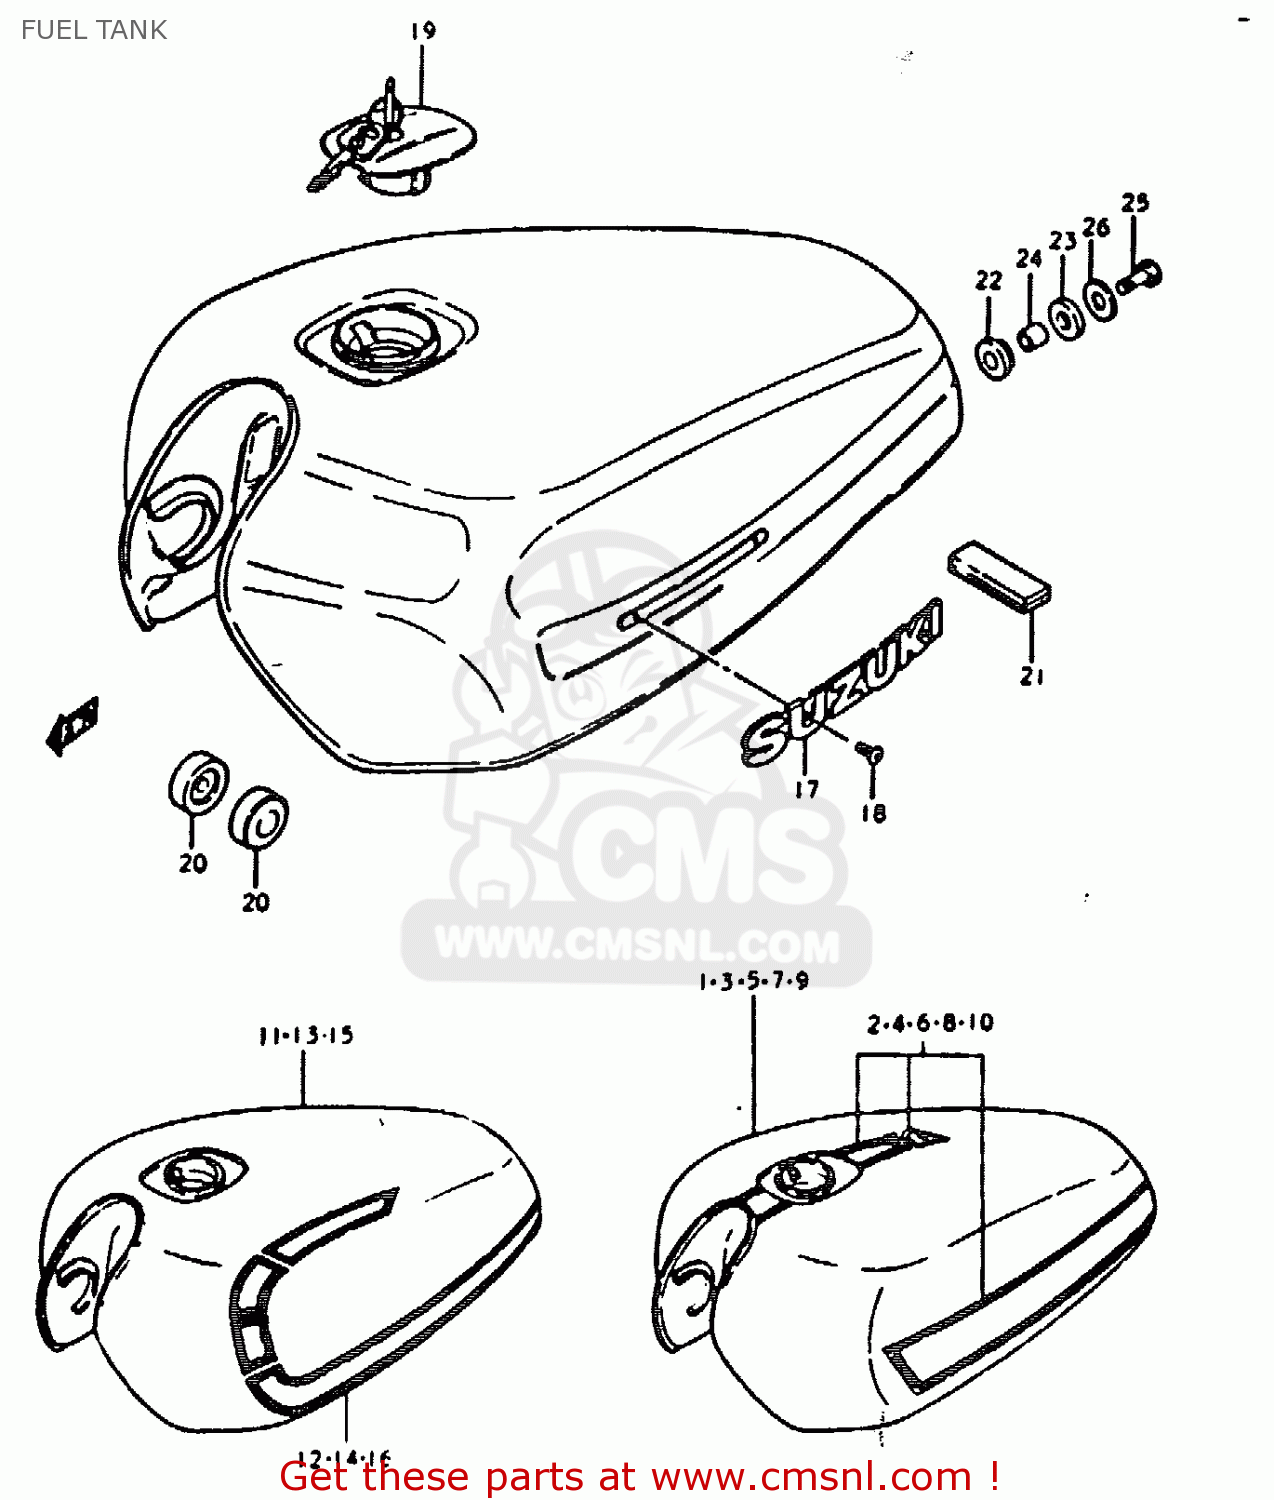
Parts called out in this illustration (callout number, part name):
10	TAPE SET
11	TANK, FUEL
12	TAPE SET
13	TANK, FUEL
14	TAPE SET
15	TANK, FUEL
16	TAPE SET
17	EMBLEM,FUEL TANK
18	SCREW 3X6
19	CAP SET,FUEL TANK
20	CUSHION
21	CUSHION
22	CUSHION
23	CUSHION
24	SPACER(8.5X12X19)
25	BOLT (8X30)
26	WASHER (8.5X29X1.6)
